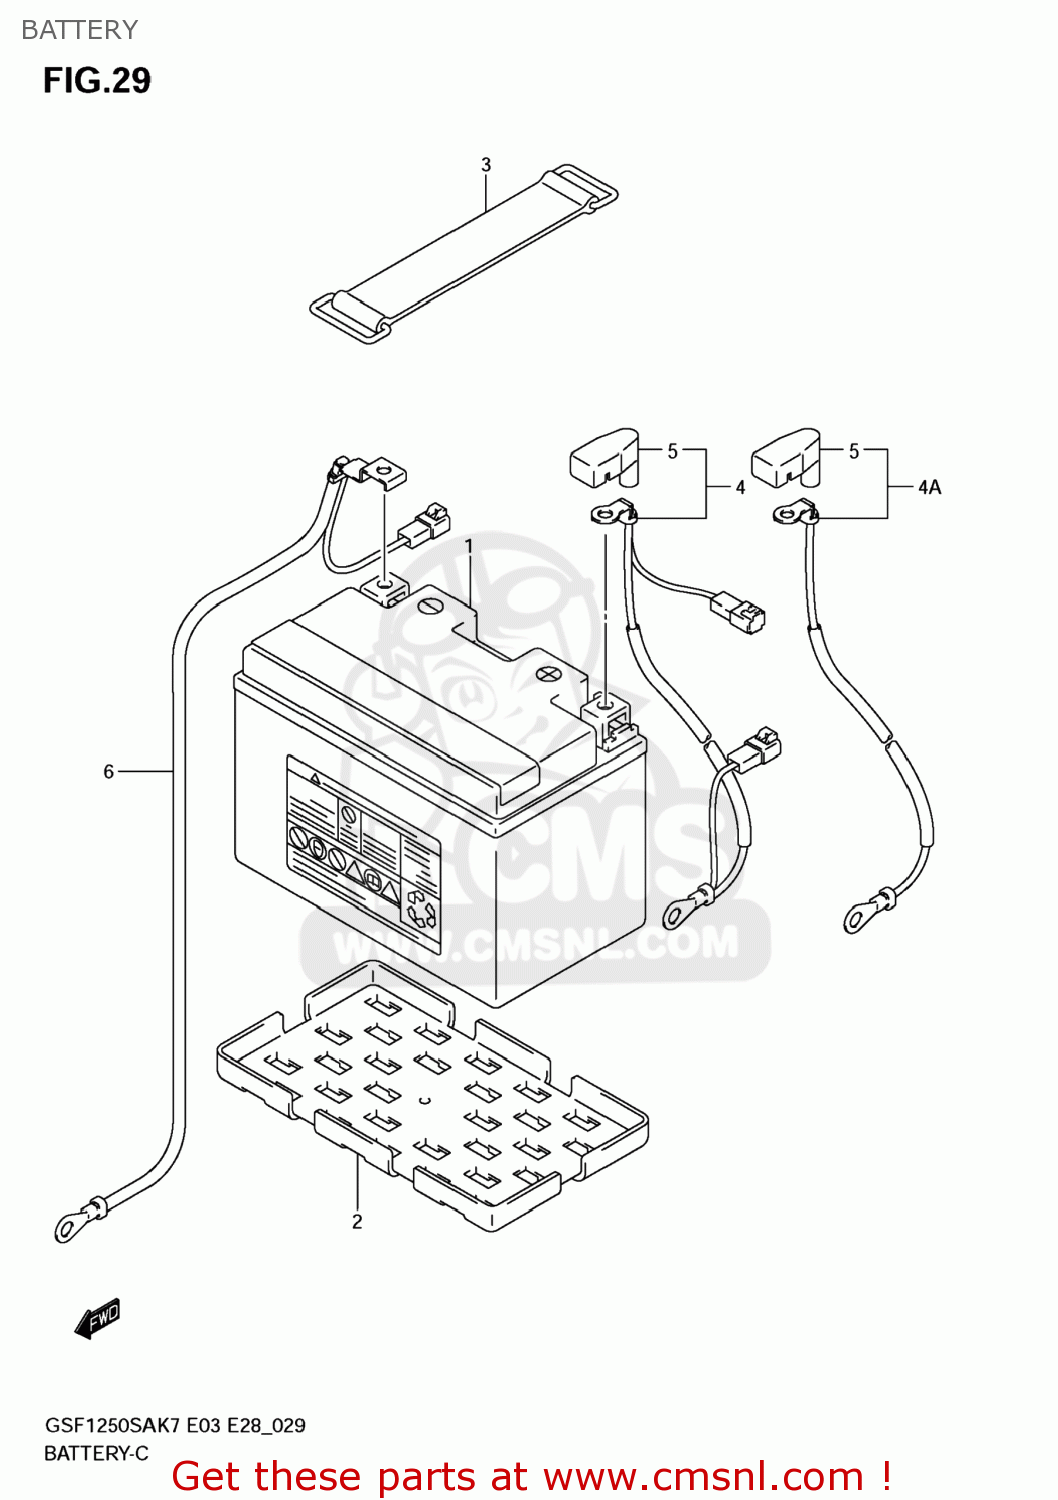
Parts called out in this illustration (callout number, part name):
1	BATTERY ASSY,F
2	PROTECTOR,BATTERY
3	BAND
4	WIRE,BATTERY PLUS LEAD
4A	WIRE,BATTERY PLUS LEAD
5	CAP,BATTERY PLUS LEAD
6	WIRE,BATTERY MINUS LEAD
